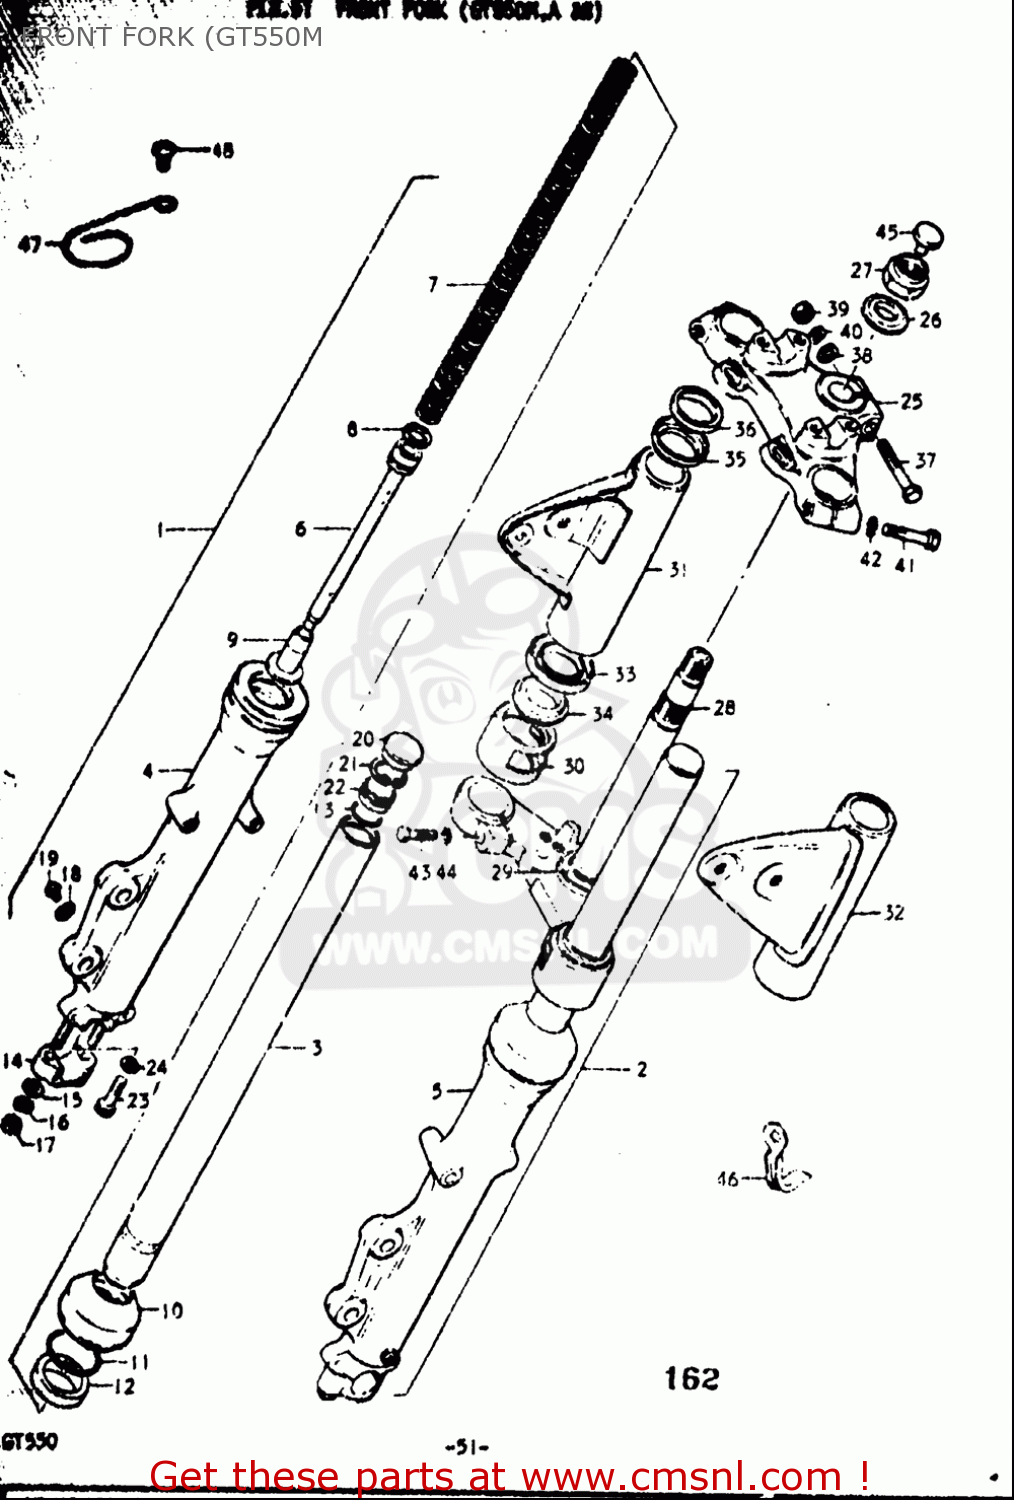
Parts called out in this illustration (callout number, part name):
8	RING
9	PIECE,OIL LOCK
10	DUST SEAL,FR FORK
11	RING,OIL SEAL STOPPER
12	SEAL,OIL 35X48X11
13	O RING
14	HOLDER,AXLE
15	WASHER
16	WASHER,LOCK
17	NUT
18	GASKET (NAS)
19	SCREW 4X6
20	CAP
21	CIRCLIP
23	BOLT(8X27)
24	GASKET (NAS)
26	WASHER
27	NUT
29	RACE,STEERING OUTER LWR
30	COVER,FORK LWR BRACKET
33	GUIDE
34	CUSHION,HEADLAMP BRACKET
35	GUIDE
36	CUSHION,HEADLAMP BRACKET UPR
37	BOLT
38	WASHER
39	NUT
40	WASHER,LOCK
41	BOLT
42	WASHER,LOCK
43	BOLT
44	WASHER,LOCK
45	CAP(OD:20)
46	LAMP ASSEMBLY
47	CLIP
48	SCREW(5X6)
